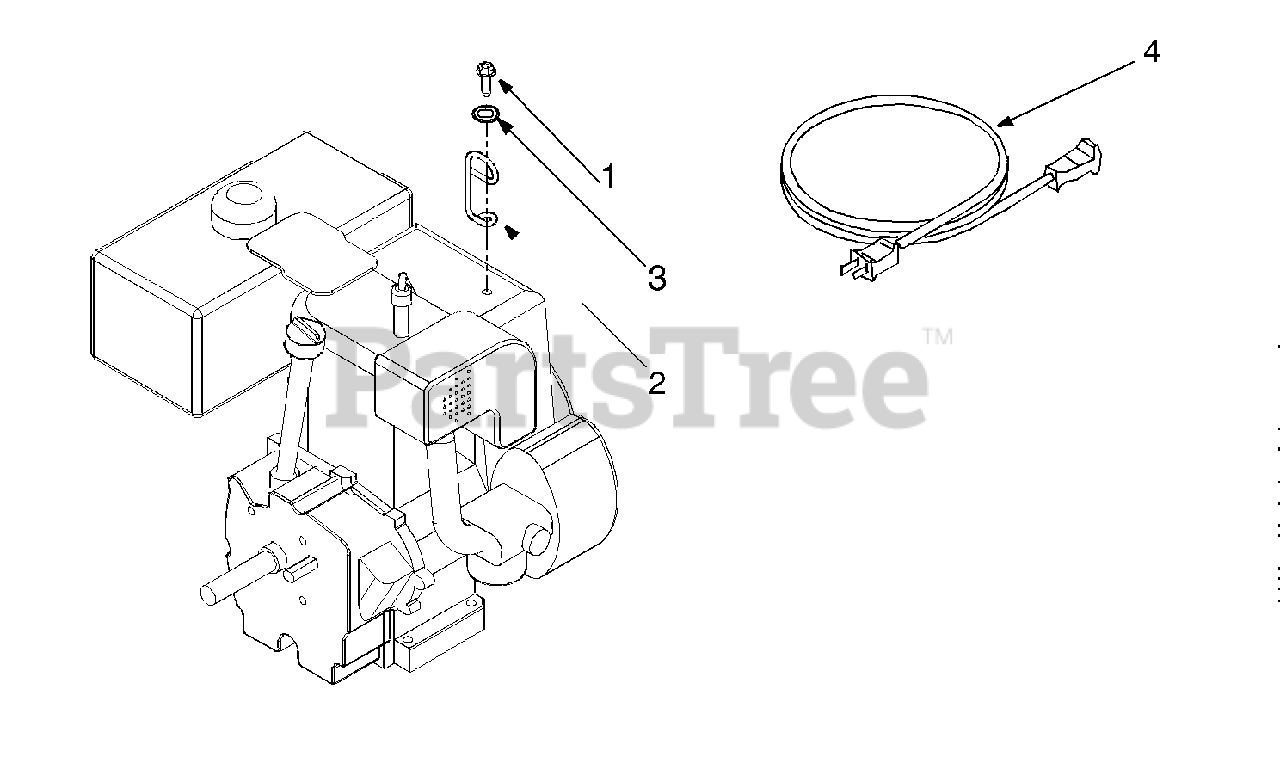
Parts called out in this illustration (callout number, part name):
1	Hex Lock Nut: 1/4-20
2	Cable Guide
3	Flat Washer
4	Extension Cord: 110V, 3-prong
